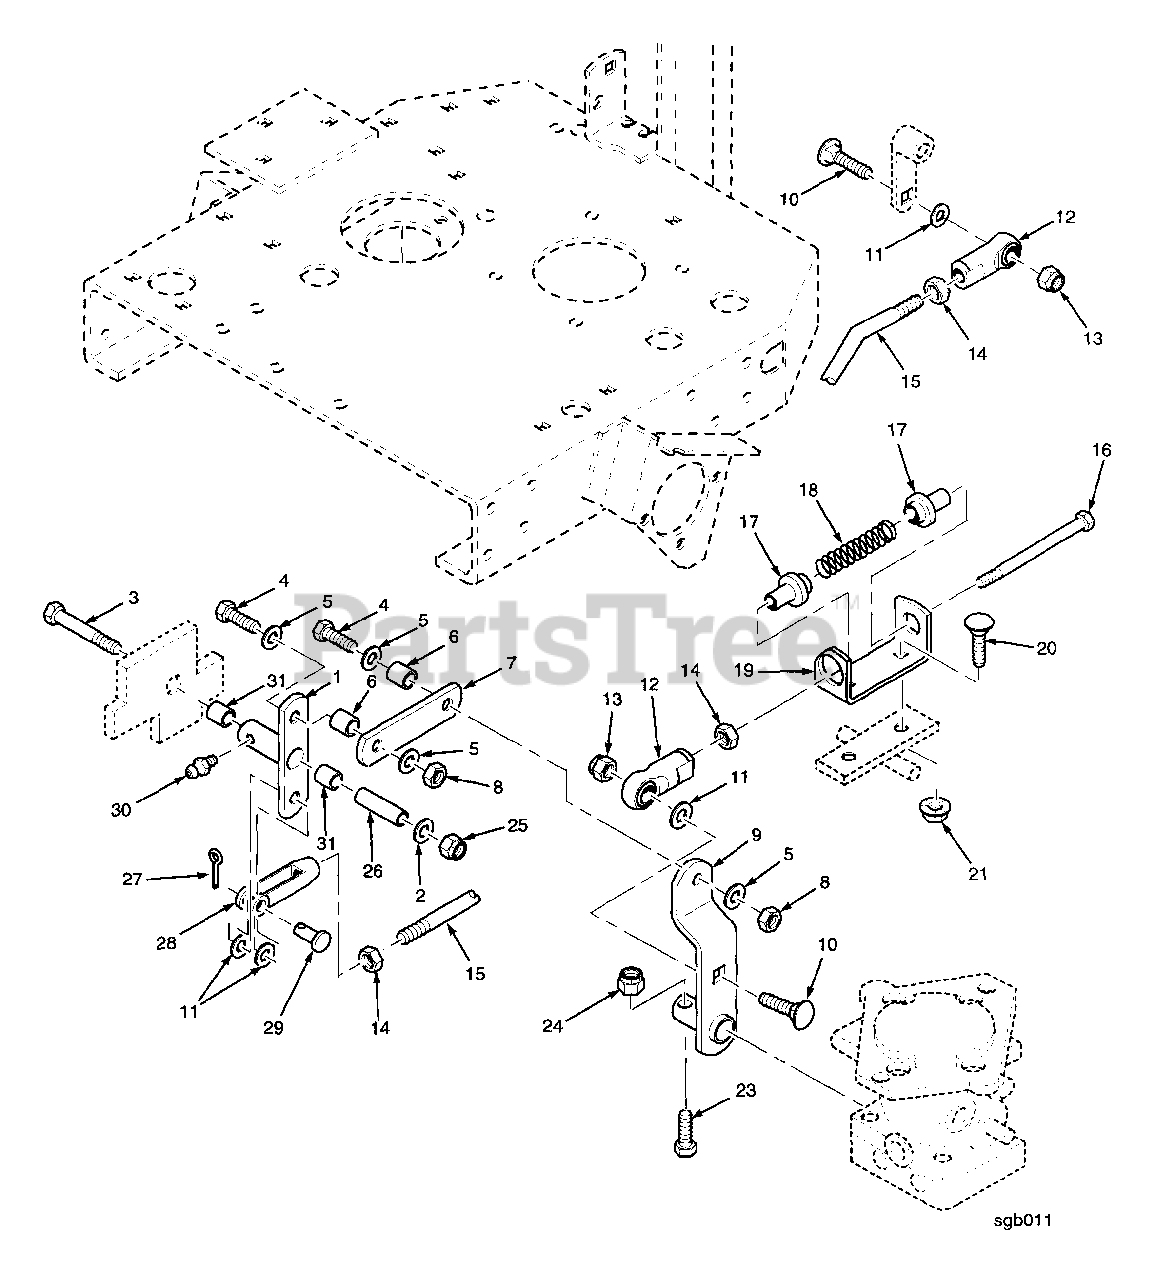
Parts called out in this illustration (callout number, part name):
1	Control Linkage, Bellcrank
2	Flatwasher, 5/16 (.375 x .875 x .083)
3	Bolt, Hex Head 5/16-18 x 2-3/4
4	Bolt, Hex Head 3/8-16 x 1
5	Flatwasher, 3/8 (.406 x .812 x .065)
6	Sleeve, Pump Control Link
7	Link, Speed Control
8	Hex Locknut, 3/8-16
9	Control Arm, Pump
10	Carriage Bolt, RH SH SQNK 3/8-16 x 1-1/2
11	Flatwasher, 3/8 (.391 x .938 x .105)
12	Rod End, RH Female THD 3/8-24
13	Hex Locknut, Elastic Stop 3/8-16
14	Hex Nut, 3/8-24
15	Control Rod
16	Bolt Hex Head, 3/8-24 x 6-3/4
17	Bushing, Spring Keeper
18	Spring, Neutral Return
19	Retainer, Neutral Spring
20	Carriage Bolt, 5/16-18 x 1
21	Serr. Fl. Hex Nut 5/16-18
23	Bolt, Hex Head 1/4-20 x 1-1/4
24	Hex Locknut, Elastic Stop 1/4-20
25	Hex Locknut, Elastic Stop 5/16-18
26	Sleeve, Control Arm
27	Cotter Pin, 3/32 x .75
28	Clevis, Pump Control
29	Pin, Clevis 3/8
30	Grease Fitting, 1/4-28 Self Tap
31	Bushing, Bronze
